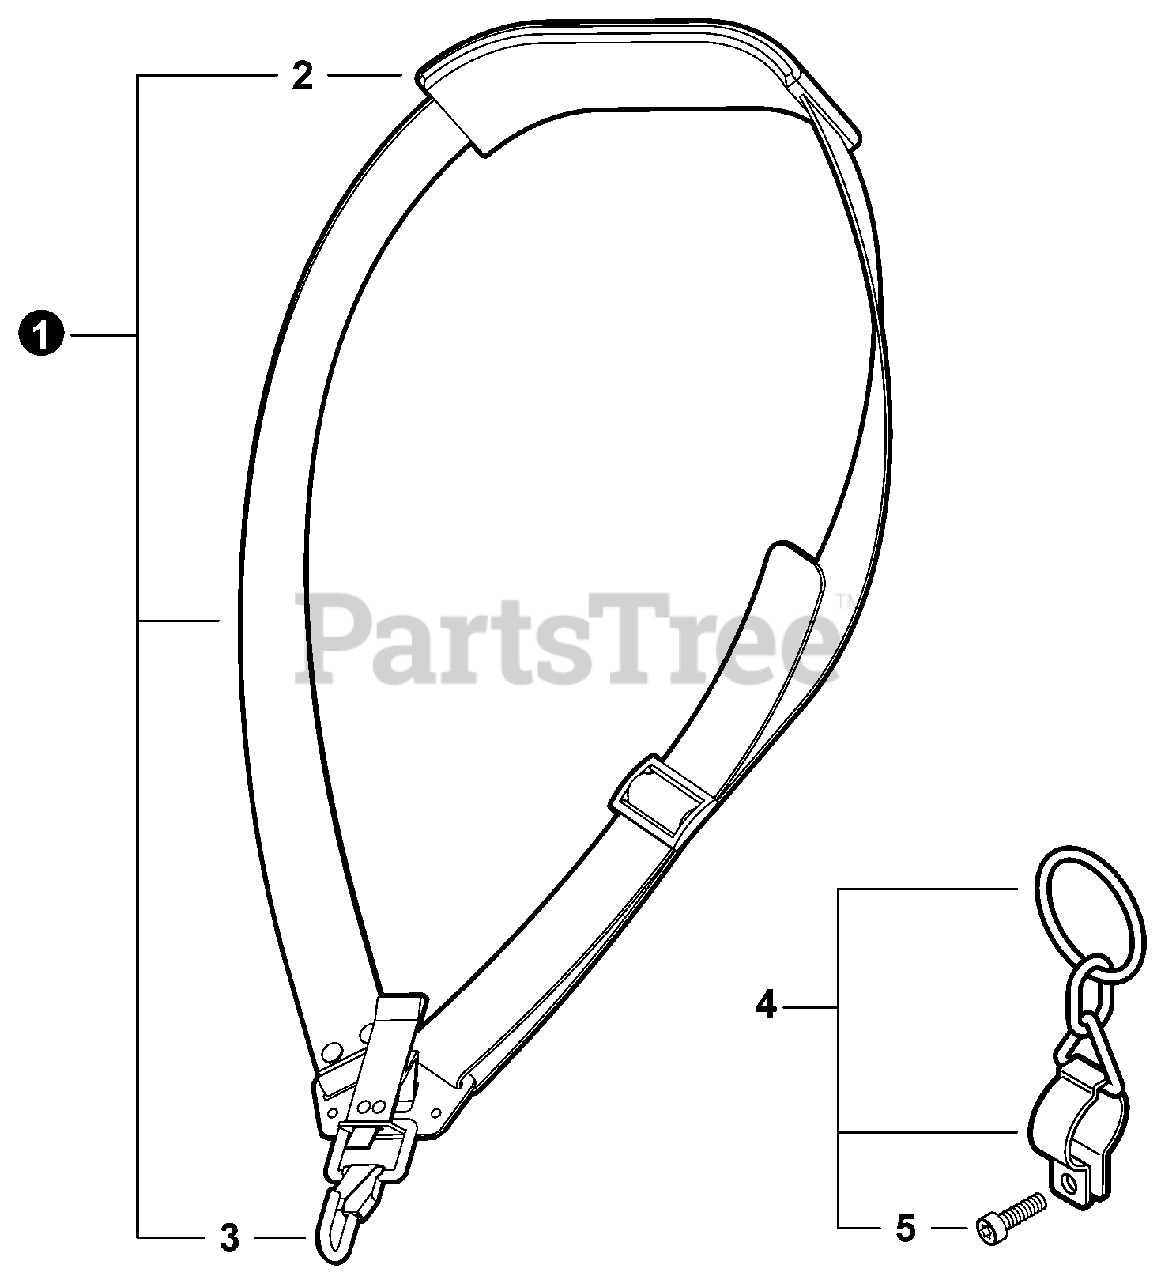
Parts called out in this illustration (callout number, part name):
1	HARNESS ASSY, SHOULDER
2	PAD, SHOULDER
3	HOOK, SNAP
4	HANGER SET, HARNESS
5	BOLT, TORX 5x12
